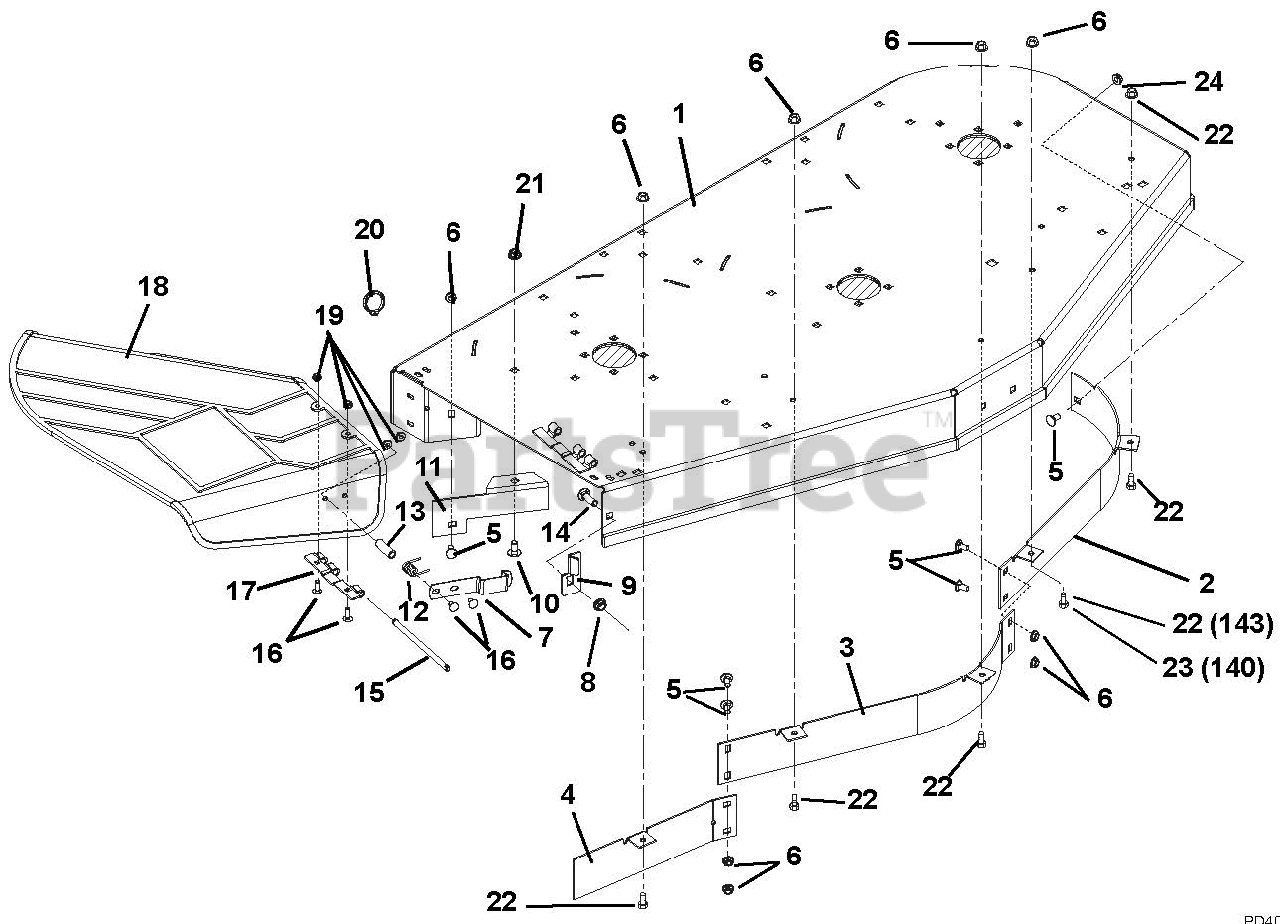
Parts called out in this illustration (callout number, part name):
1	Weldment, Deck 48"
1	Weldment, Deck 44"
2	Baffle, Left Front 48"
2	Baffle, Left Front 44"
3	Baffle, Center Front 48"
3	Baffle, Center Front 44"
4	Baffle, Right Front 48"
4	Baffle, Right Front 44"
5	Bolt-Round Head Square Neck .31-18 x .62 Grade 5
6	Nut, .312-18 Flange Nyloc
7	Flat Spring
8	Nut, Locking Top Flange .38-16
9	Bracket, Chute Lock
10	Bolt-Round Head Square Neck .38-16 x .75
11	Deflector, 44"/48"
12	Spring, Torsion .095 x .50 x 1.00
13	Bushing, Sleave .334 x .502 x 1.437
14	Bolt-Round Head Square Neck .38-16 x 1.25 Grade 5
16	Bolt-Round Head Square Neck .25-20 x .75 Grade 5
17	Hinge Plate
18	Deflector, Chute 42"
19	Nut, Nyloc Flange .25-20
20	Ring, Retaining Exterior
21	Nut, .38-16 Flange Nyloc
22	Bolt, Hex .31-18 x .75 Grade 5
23	Bolt, Hex .31-18 x 1.00 Grade 5
24	Nut, Center Locking Jam .31-18
